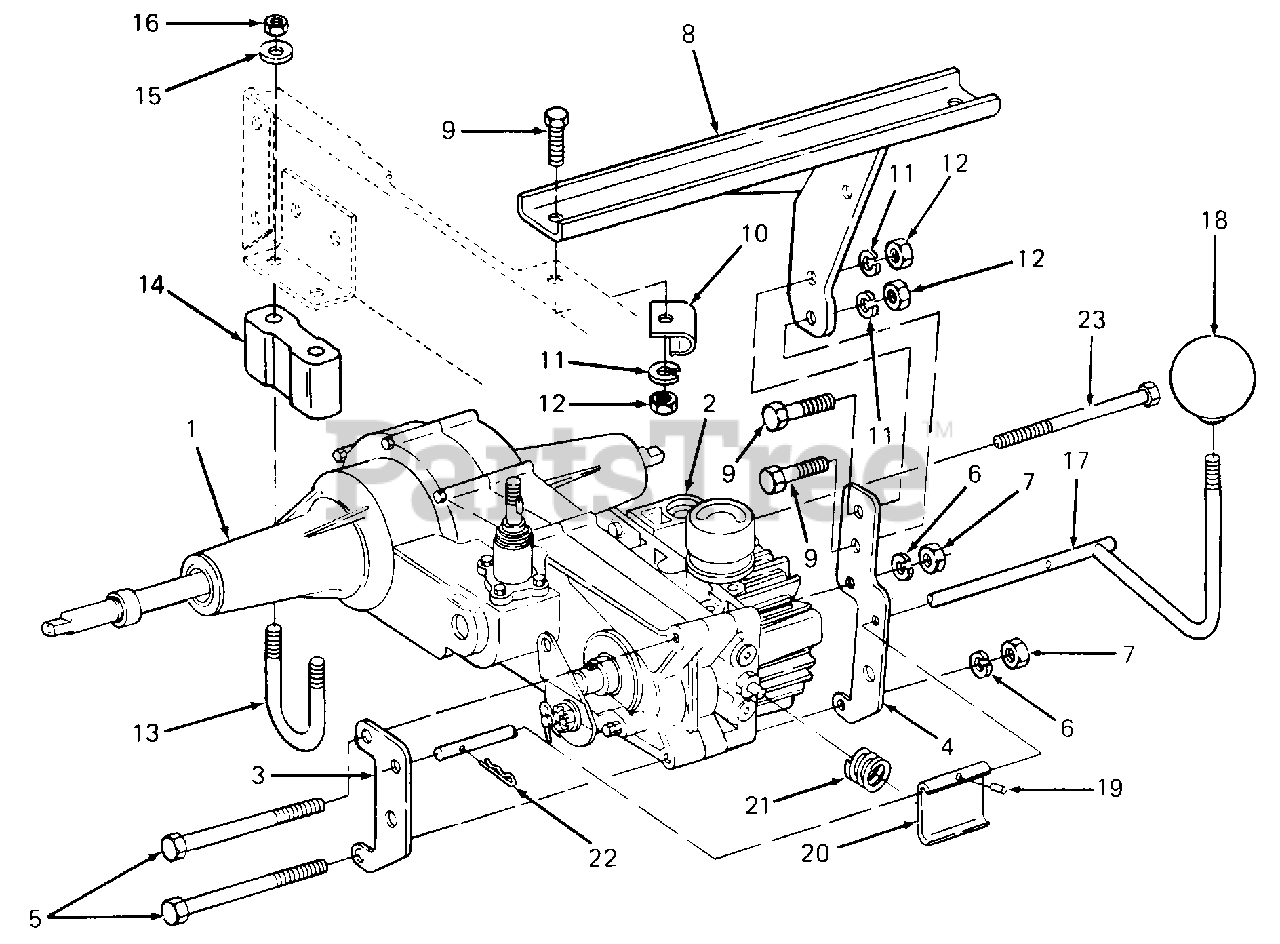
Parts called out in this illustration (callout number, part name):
1	Transaxle
2	Pump, Hydro
3	Bracket, Transmission Dump Valve
4	Bracket, Transmission Dump Valve Torque
5	Screw, Hex Cap, 5/16-18 x 4.5 Lg GR5
6	Washer, Lock, 5/16
7	Nut, Hex, 5/16-18 GR5
10	Clip, Cable
11	Washer, Lock, 3/8
12	Nut, Hex, 3/8-16 GR5
13	U-Bolt, 5/16-18 x 2.75 Lg
14	Spacer, Axle
15	Washer, Bell, .345 x .88 x .06 Thk
16	Nut, Hex Center Lock, 5/16-18 GR5
17	Rod, Dump Valve
18	Knob, Ball, 1/4-20 Trd
19	Pin, Spiral Spring, 1/8 Dia x .75 Lg
20	Lever, Dump Valve
21	Spring, Compression
22	Pin, Internal Cotter
23	Bolt, Hex Patch, 5/16-18 x 4.5 Lg GR5
